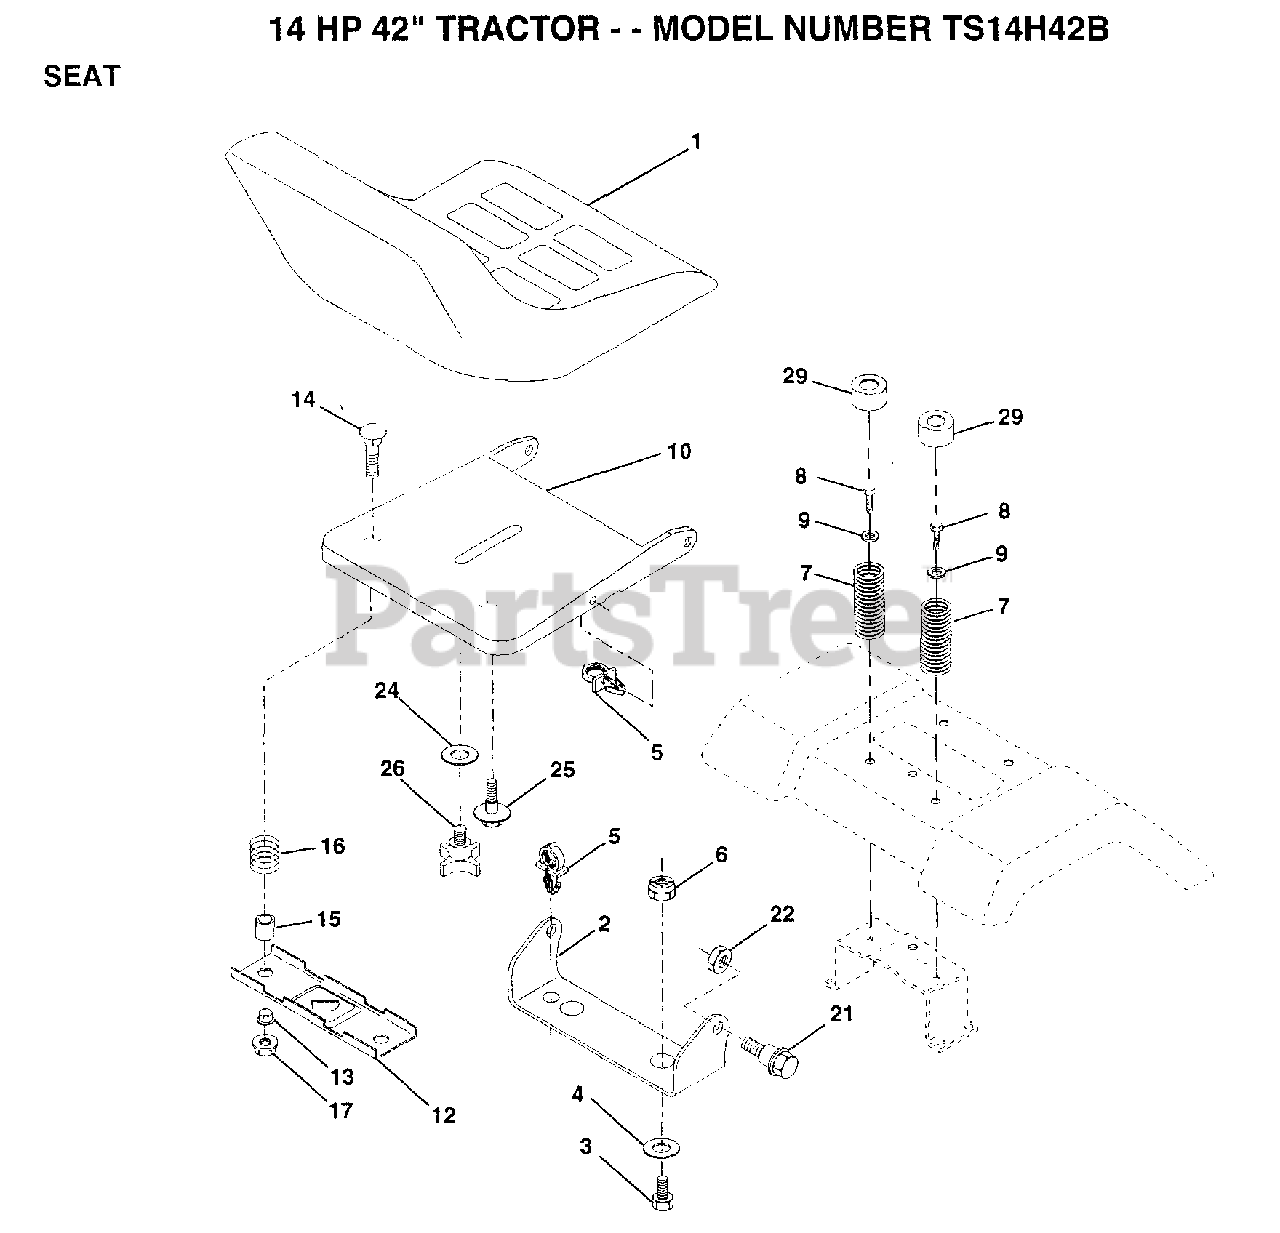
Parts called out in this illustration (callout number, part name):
2	BRACKET PVT SEAT
3	BOLT
4	WASHER PM
5	CLIP PUSH - IN
6	NUT
7	SPRING COMPRESSIO
8	SCREW GTV
9	WASHER
12	BRKT SWITCH
13	BUSHING
15	SPLIT SPACER
16	SPRING
21	BOLT.SHLD.5/16-18
22	NUT
24	WASHER
25	"BOLT,SHOULDER"
26	"KNOB 1/2"" YT"
29	CAP SPRING
